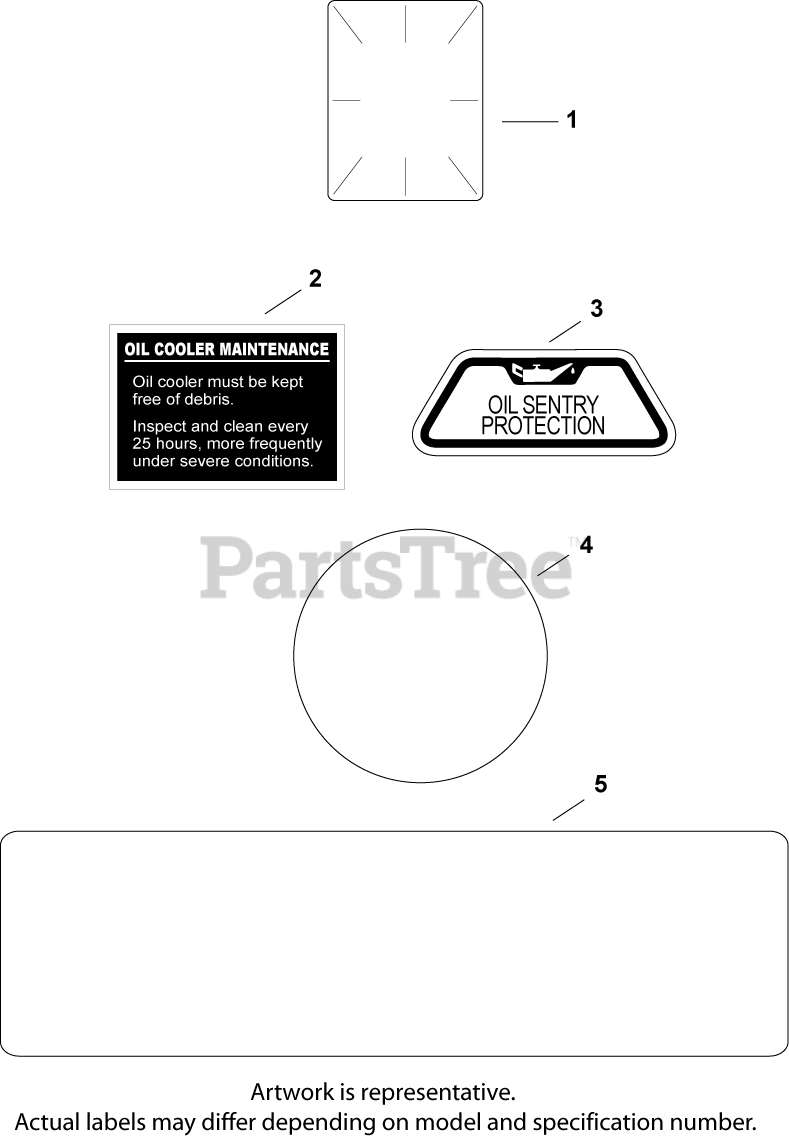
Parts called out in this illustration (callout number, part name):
1	DECAL, CLEAR LAMINATE USE 25 113 70-S
2	DECAL, OIL COOLER - (#DSC)
3	DECAL, OIL SENTRY - (#DSC)
4	DECAL, GRASS SCREEN USE 24 113 499-S
5	DECAL, 23 HP - DISCONTINUED
